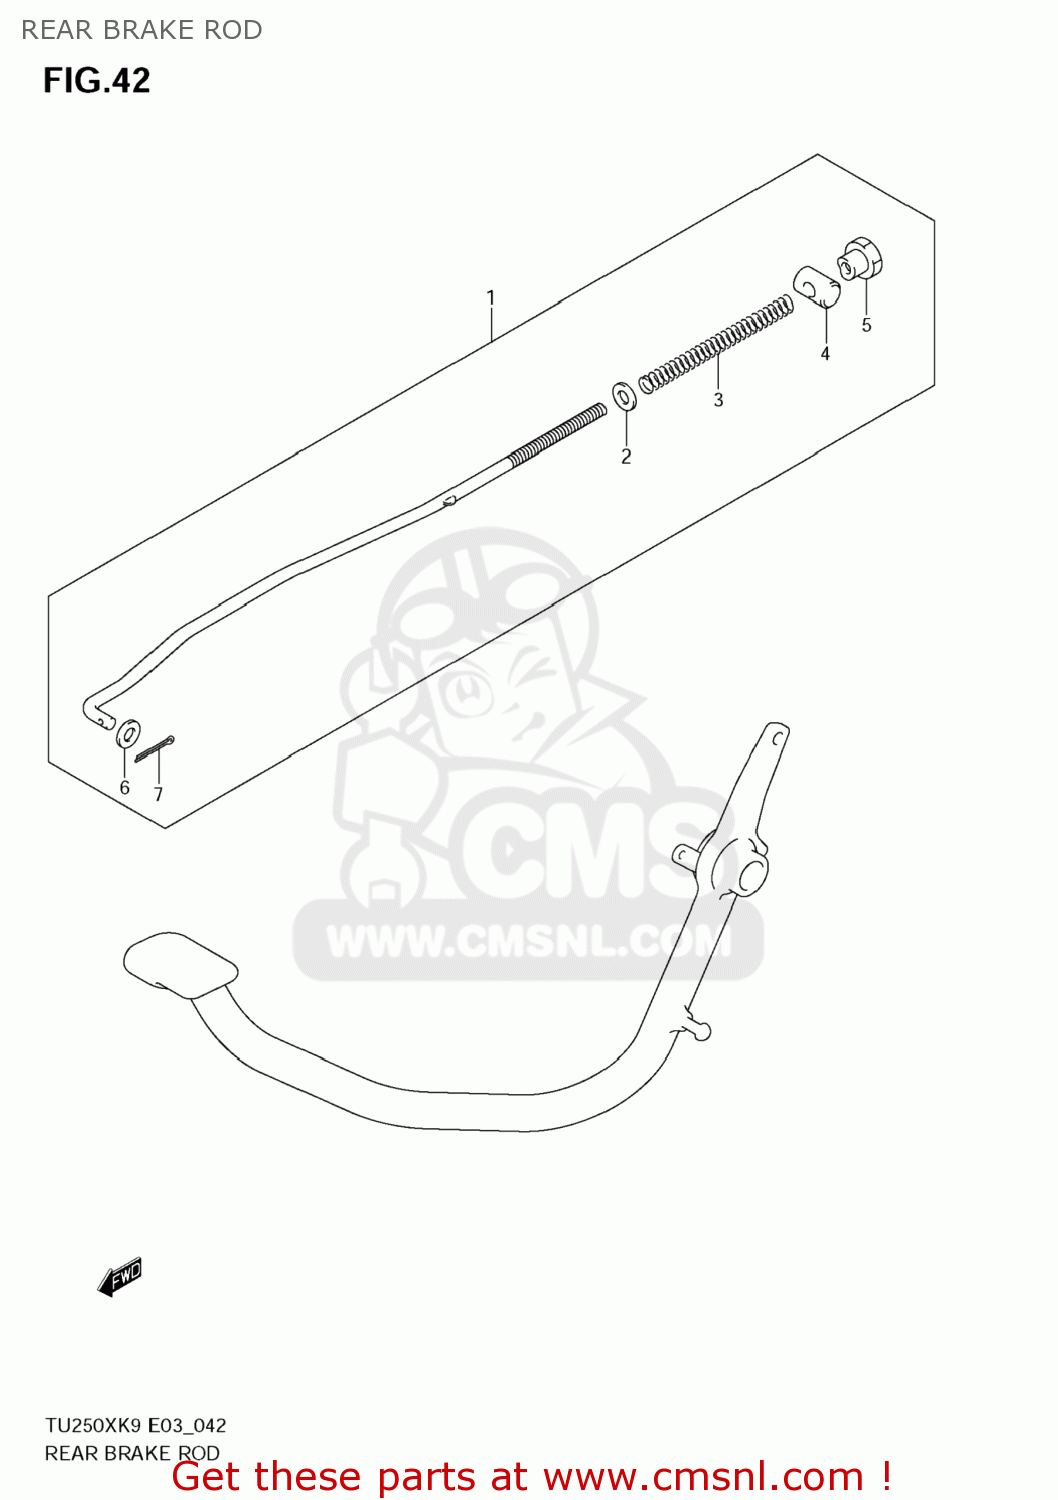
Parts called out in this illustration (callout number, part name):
1	ROD ASSY,RR BRAKE
2	WASHER
3	SPRING
4	PIN(11X18)
5	NUT
6	WASHER
7	PIN
